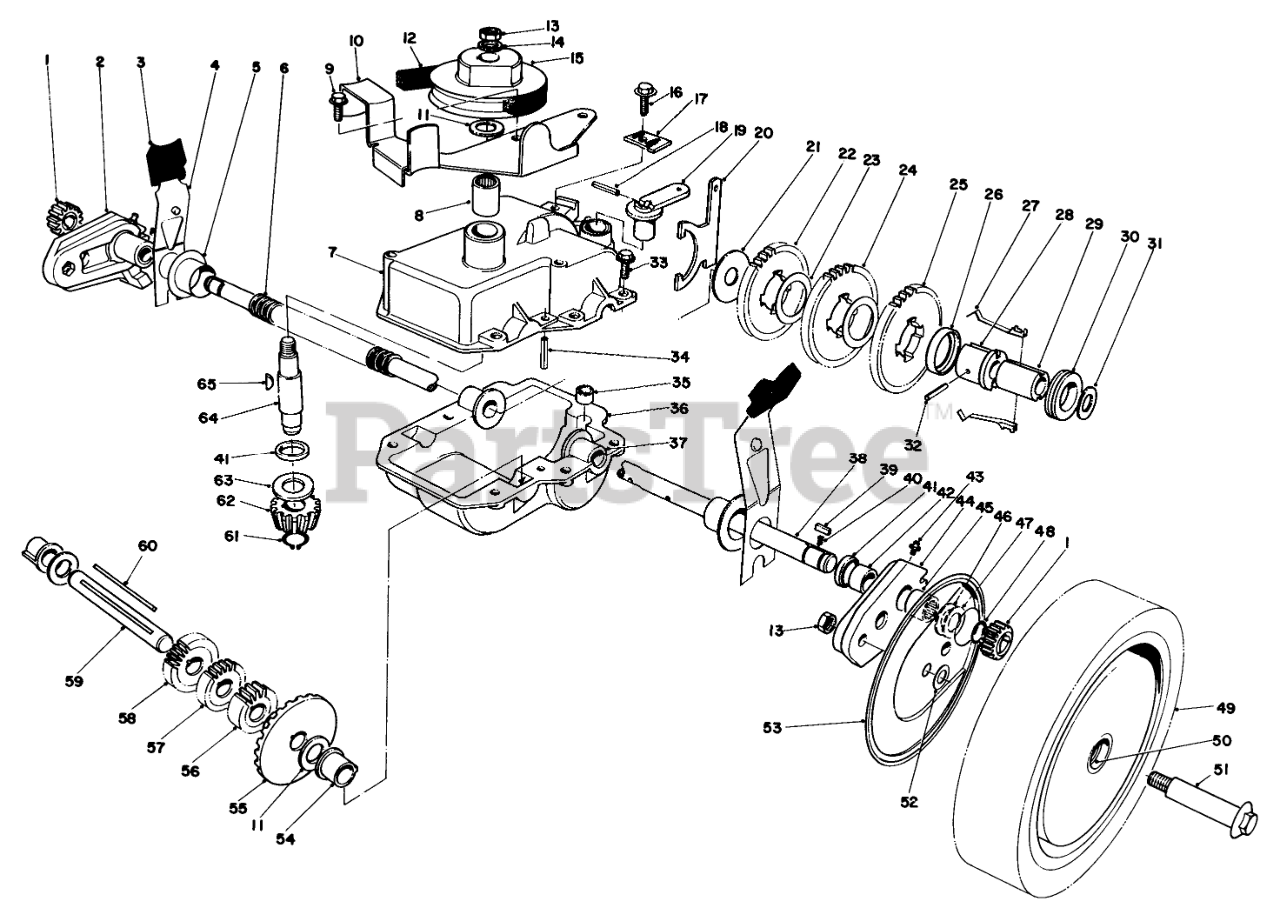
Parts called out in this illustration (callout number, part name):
1	GEAR-PINION
2	Pivot Arm Assembly-R.H. (Incl. Ref. #41-43 & 45)
3	KNOB-ARM
4	SPRING ARM ASM SP
5	CAP-END
6	CONDUIT-CONVOLUTED, SPLIT
7	Case-Upper
8	BEARING
9	SCREW
10	Bracket-Belt Guide
11	WASHER-THRUST
12	V-BELT
13	Nut
14	WASHER-FLAT
15	PULLEY
16	SCREW-HWHTF
17	Cable Clamp
18	PIN-COIL
19	LEVER-SHIFT
20	Shift Yoke
21	WASHER
22	GEAR-38T
23	WASHER
24	GEAR-42T
26	KEY RETAINER
27	Key
28	Body-Sleeve
29	SLEEVE
30	COLLAR-SHIFT
31	WASHER-PLAIN
32	PIN-SPRING
33	SCREW-HWH, THREAD ROLL
34	ROLL PIN 3/16 X 1 IN
35	BUSHING-YOKE
36	LOWER GEAR CASE CAST
37	Bushing-Output Shaft
38	Output Shaft
39	KEY RECTANGULAR
40	SPRING-COMPRESSION
42	BUSHING
43	FITTING-GREASE
44	Pivot Arm Assembly-L.H.(Incl. Ref. #41-43 & 45)
45	BEARING-ROLLER
46	Washer
47	THRUST WASHER
48	Retaining Ring
49	Wheel, Tire 8 Gear Assembly (Incl. Ref. #50)
50	BUSHING
51	BOLT-WHEEL
52	WASHER
53	WHEEL COVER
54	BUSHING
55	BEVEL GEAR
56	GEAR-12T
57	GEAR-14T
58	GEAR-18T
59	INTERMEDIATE SHAFT
60	Key Square
61	RING-RETAINING
62	PINION-BEVEL
63	WASHER-THRUST
64	INPUT SHAFT
65	KEY-WOODRUFF
